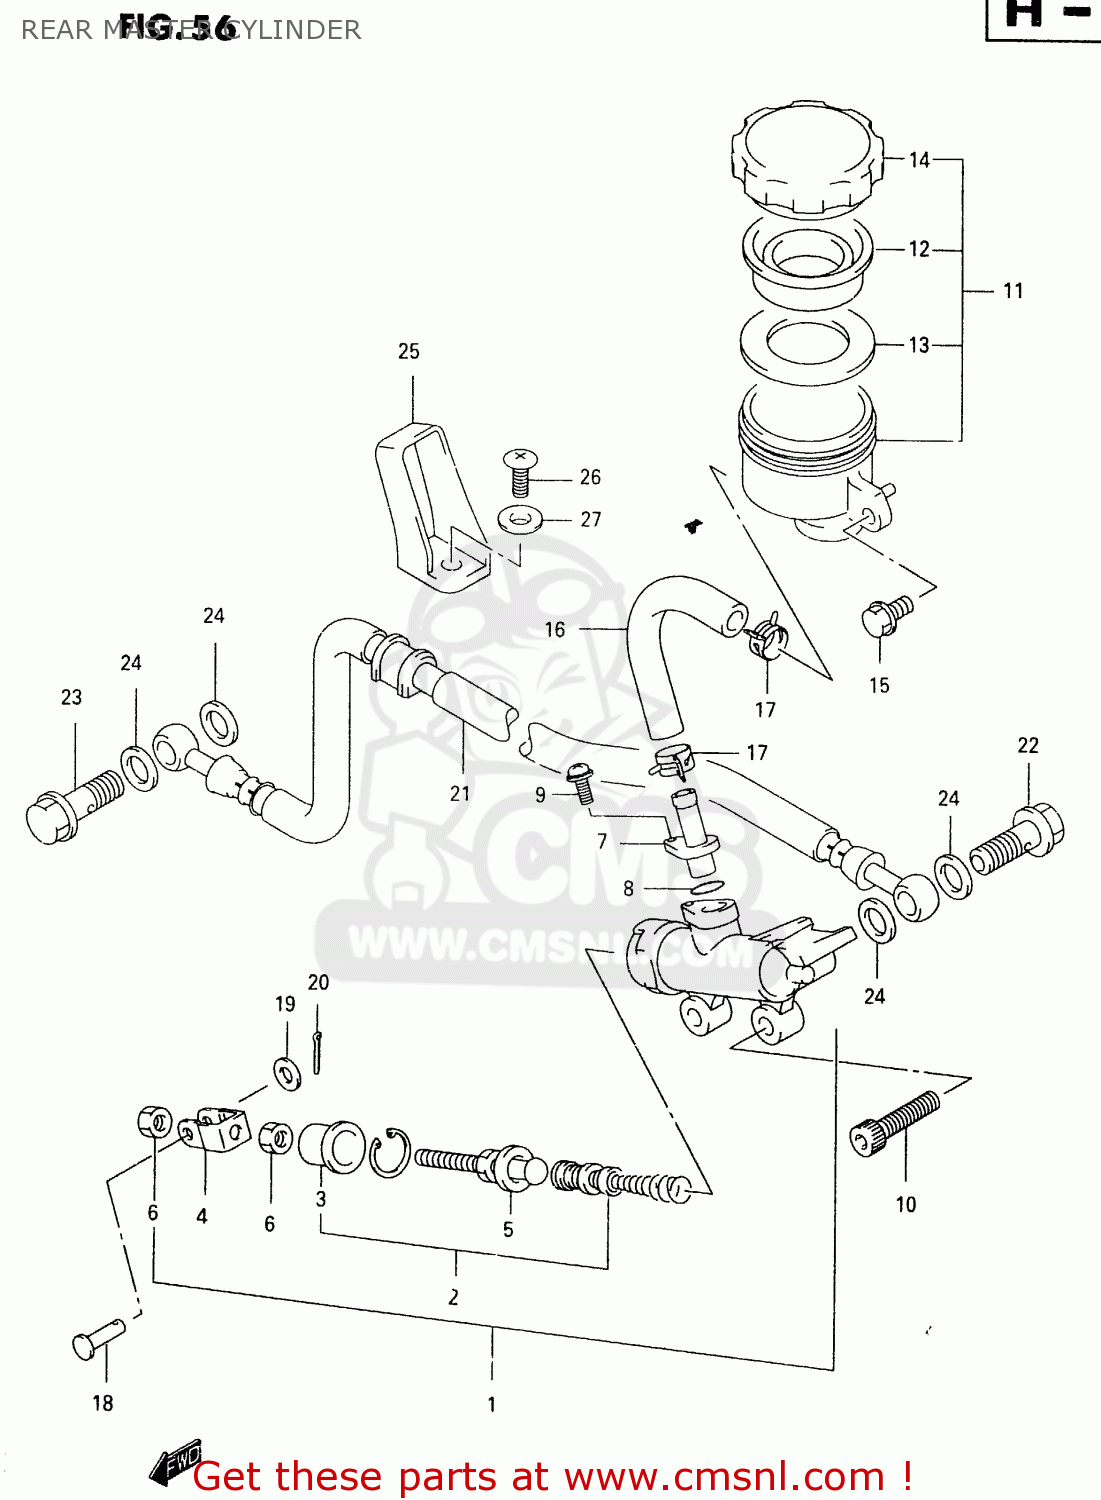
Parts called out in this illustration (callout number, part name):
1	CYLINDER ASSY,RR MASTER
2	PISTON/CUP SET
3	BOOT
4	YOKE
5	ROD,PUSH
6	NUT
7	CONNECTOR
8	O RING
9	SCREW
10	BOLT(6X16)
11	TANK ASSY,RR RESERVOIR
12	DIAPHRAGM
13	PLATE,DIAPHRAGM
14	CAP
15	BOLT
16	HOSE,RESERVOIR TANK
17	CLIP
18	PIN
19	WASHER
20	PIN
21	HOSE COMP,REAR BRAKE
22	BOLT UNION
23	BOLT UNION
24	WASHER(10X15X1.5)
25	GUIDE,RR BRAKE HOSE
26	SCREW
27	WASHER
